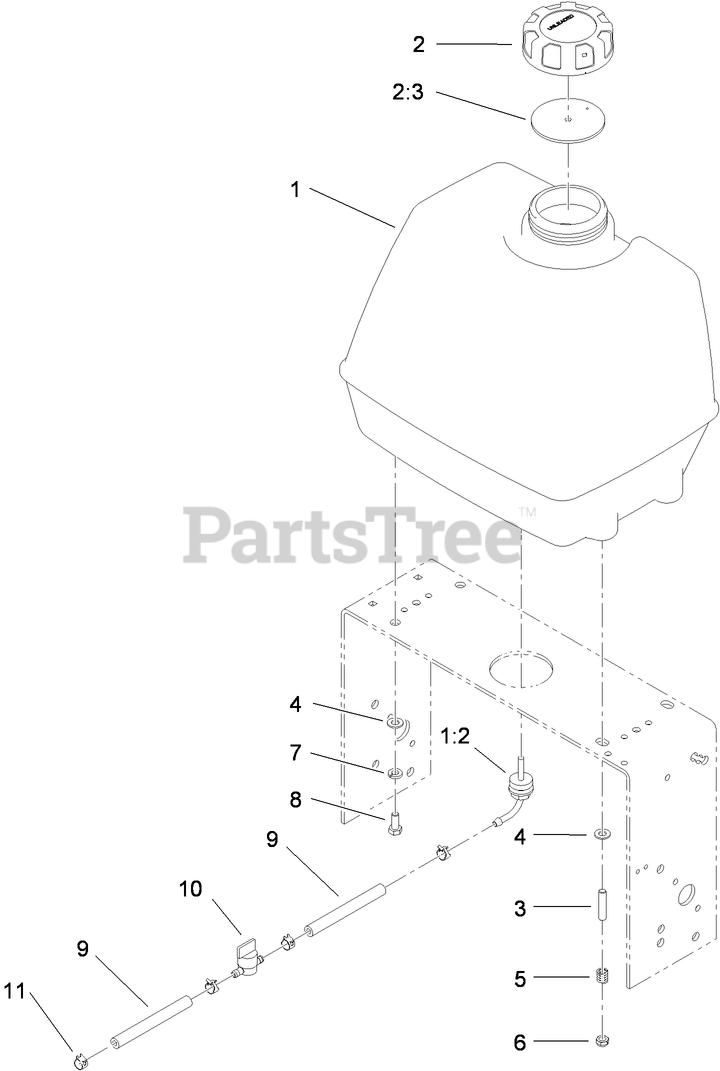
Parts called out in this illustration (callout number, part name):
1	FUEL TANK ASM
1:2	FITTING-FUEL, BULKHEAD
2	GAS CAP ASM
2:3	GASKET-CAP, GAS
4	WASHER-PLAIN
5	SPRING-TANK, FUEL
6	NUT-LOCK, NI
7	WASHER-LOCK
8	SCREW-HH
9	HOSE-FUEL
10	VALVE-FUEL
11	CLAMP-HOSE
